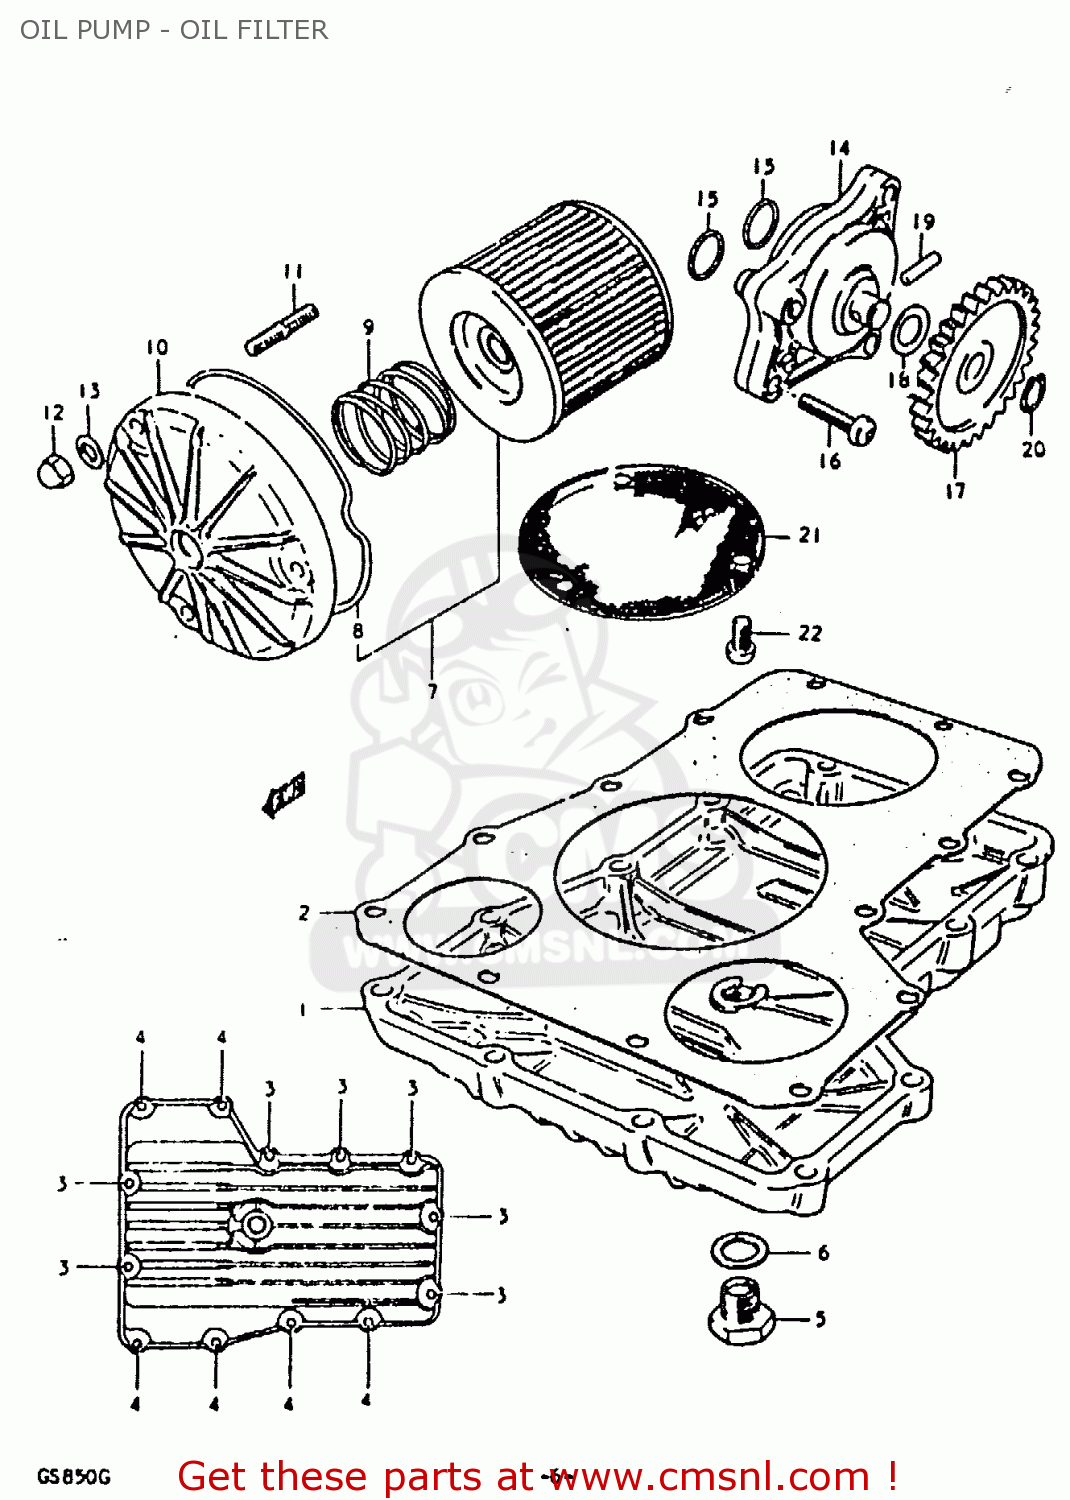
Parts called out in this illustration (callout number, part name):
1	PAN,OIL
2	GASKET,OIL PAN (MCA)
3	BOLT
4	BOLT
5	PLUG
6	GASKET(14X19.2X2) (NAS)
7	ENGINE OIL FILTER SET
8	O RING,OIL FILTER CHAMBER CAP
9	SPRING
10	CAP,OIL FILTER
11	STUD 6X20
12	NUT
13	WASHER
14	PUMP ASSEMBLY,OIL
15	O RING(D:1.9,ID:13)
16	SCREW
17	GEAR,OIL PUMP DRIVEN
18	SHIM
19	PIN(4X15.8)
20	CIRCLIP
21	STRAINER,ENGINE OIL
22	SCREW 6X12
